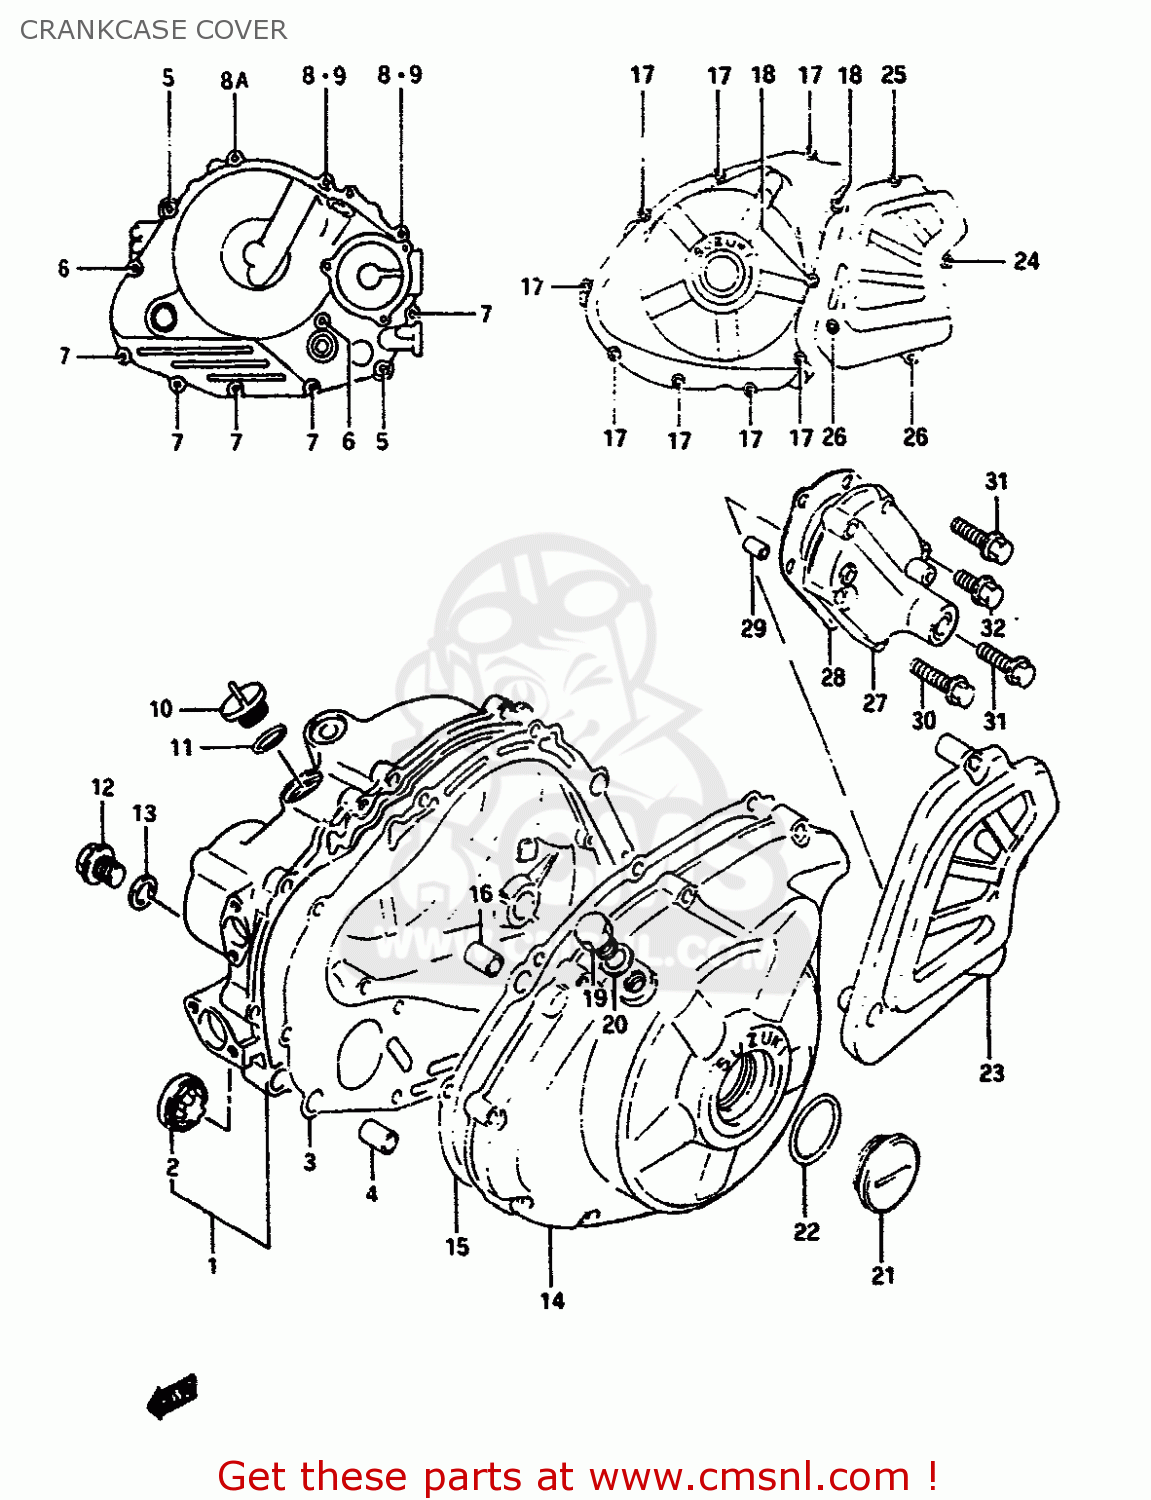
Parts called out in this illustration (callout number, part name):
1	COVER,CLUTCH
2	LENS,OIL LEVEL CHECK
3	GASKET,CLUTCH COVER
4	PIN
5	BOLT 6X50
6	BOLT 6X40
7	BOLT 6X35
8	BOLT 6X25
8A	BOLT 6X25
9	GASKET(5.8X13X1.2) (NAS)
10	PLUG
11	O RING(D:3.1,ID:16.8)
12	PLUG(14X12)
13	GASKET(14X19.2X2) (NAS)
14	COVER,GENERATOR
15	GASKET,MAGNETO COVER (MCA)
16	PIN
17	BOLT 6X30
18	BOLT 6X25
19	PLUG(12X9)
20	GASKET(12.1X16.2X3.7) (NAS)
21	PLUG
22	O RING(D:3.1,ID:32.7)
23	COVER,ENGINE SPROCKET
24	BOLT
25	BOLT 6X35
26	BOLT 6X20
27	COVER,GEAR SHIFT
28	GASKET,GEAR SHIFT COVER (MCA)
29	PIN
30	BOLT 6X35
31	BOLT 6X30
32	BOLT 6X20
